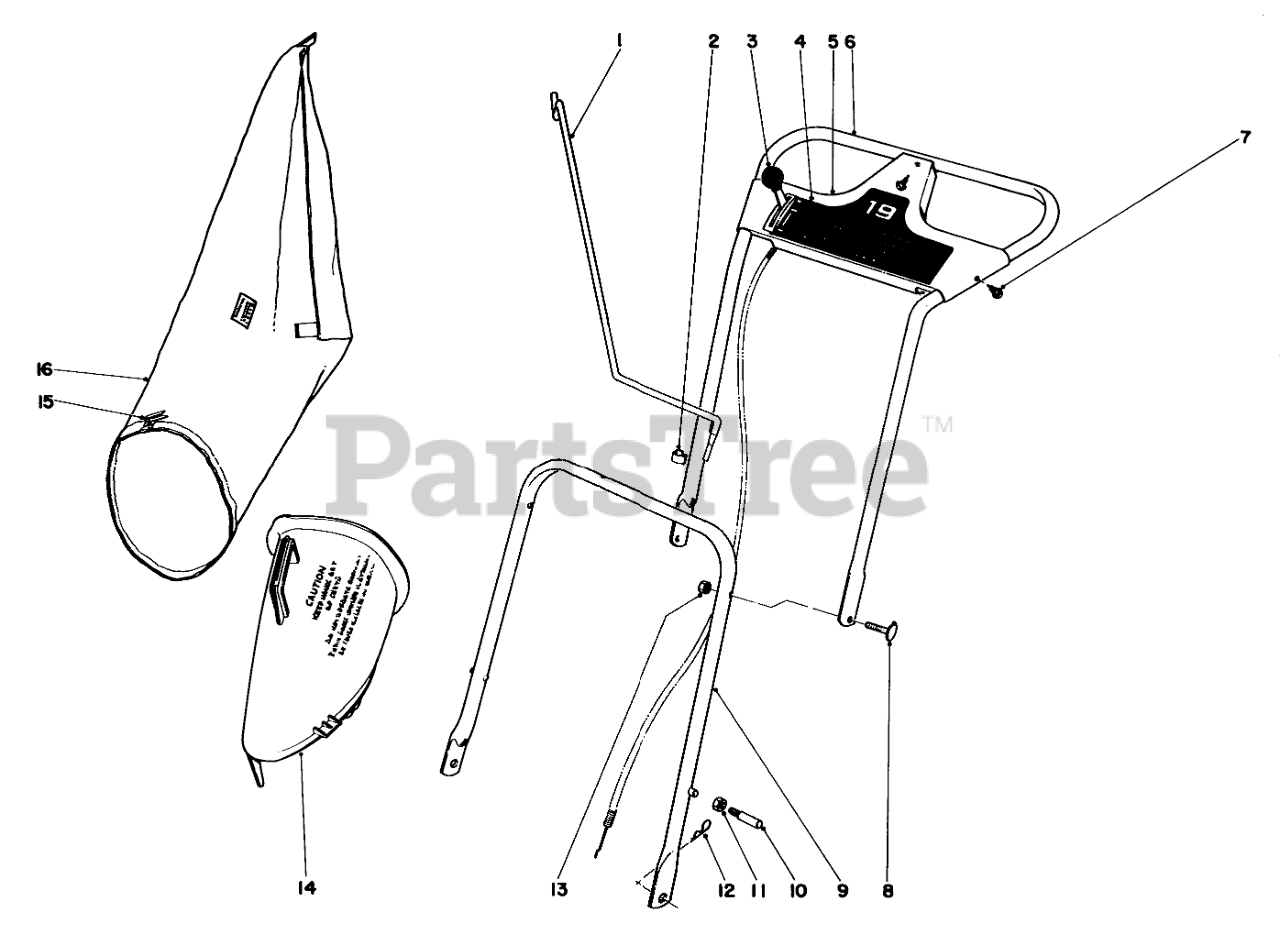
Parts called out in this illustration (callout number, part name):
1	BAG HANGER ROD
2	CONTROL WIRE CLIP
3	Throttle Control
4	Decal
5	Escutcheon Plate
6	Upper Handle
7	SCREW-HWHTF
8	1-1/4 LG HANDLE SCREW
9	Lower Handle
10	Handle Pin
11	Nut
12	PIN-COTTER, HAIR
13	Nut
14	BAG ATTACHMENT
15	BAG CORD FASTENER
16	Grass Bag (Incl. Ref. No. 15)
